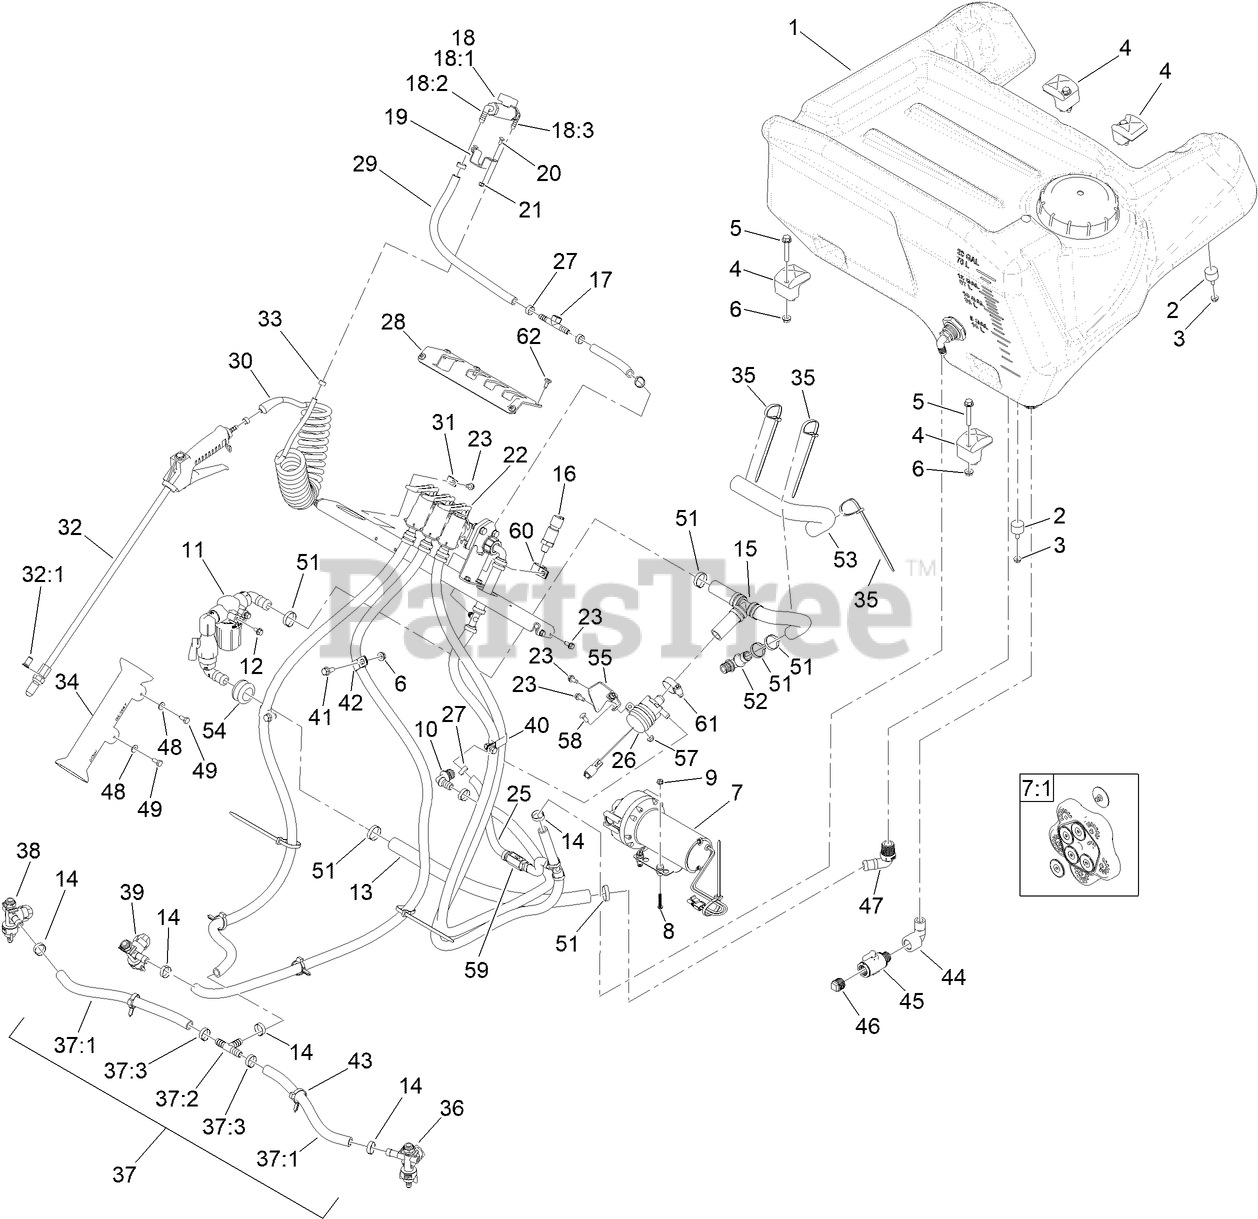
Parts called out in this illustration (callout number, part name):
1	TANK-SPRAYER
2	BUMPER
3	NUT-HF
5	SCREW-HHF
6	NUT-HF
7	PUMP-DIAPHRAGM, 3.8 GPM
7:1	KIT-DIAPHRAM PUMP
8	SCREW-SHWH
9	NUT-HF
10	FITTING-ELBOW, BARBED
11	STRAINER ASM
12	SCREW-HHF
13	HOSE-WATER
14	CLAMP OETIKER 0.716" CLOSED 0.826" OPEN
15	ASM-, 3/4 PVC REINFORCED WATER HOSE
16	TRANSDUCER-PRESSURE
17	FITTING-TEE
18	WAND CONTROL ASM
18:1	VALVE-BALL
18:2	FITTING-ELBOW-90
18:3	FITTING-ELBOW-90
19	BRACKET-VALVE
20	BOLT-CARR
21	NUT-LOCK, NI
22	MANIFOLD-VALVE, CONTROL ASM
23	SCREW-HWH
25	HOSE-WATER
26	PUMP-CENTRIFUGAL
28	COVER-CONTROLS
29	HOSE-WATER, 3/8 PVC RED
30	HOSE-COILED
31	CLAMP-R
32	SPRAY WAND ASM
32:1	STRAINER-NOZZLE, 50M 5PSI CHECK
34	HOLDER-WAND
35	TIE-CABLE
36	LEFT NOZZLE SUB ASM
37	HOSE ASM
37:1	HOSE-WATER
37:2	FITTING-TEE
37:3	CLAMP OETIKER 0.716" CLOSED 0.826" OPEN
38	RIGHT NOZZLE SUB ASM
39	CENTER NOZZLE SUB ASM
41	SCREW-HHF
42	CLIP-LOOM
43	CLAMP-HOSE
44	ELBOW-90 DEG
45	MICROVALVE
47	ELBOW-HOSEBARB
48	WASHER-FLAT
49	SCREW-HH
52	FITTING-ELBOW
53	SLEEVE-CORRUGATED, SPLIT
54	GROMMET
55	BRKT-RECIR PUMP
57	NUT-HF
58	SCREW-CARR
59	VALVE-3/8 CHECK
60	R-CLAMP
61	CLAMP-HOSE
62	SCREW-SHOULDER
